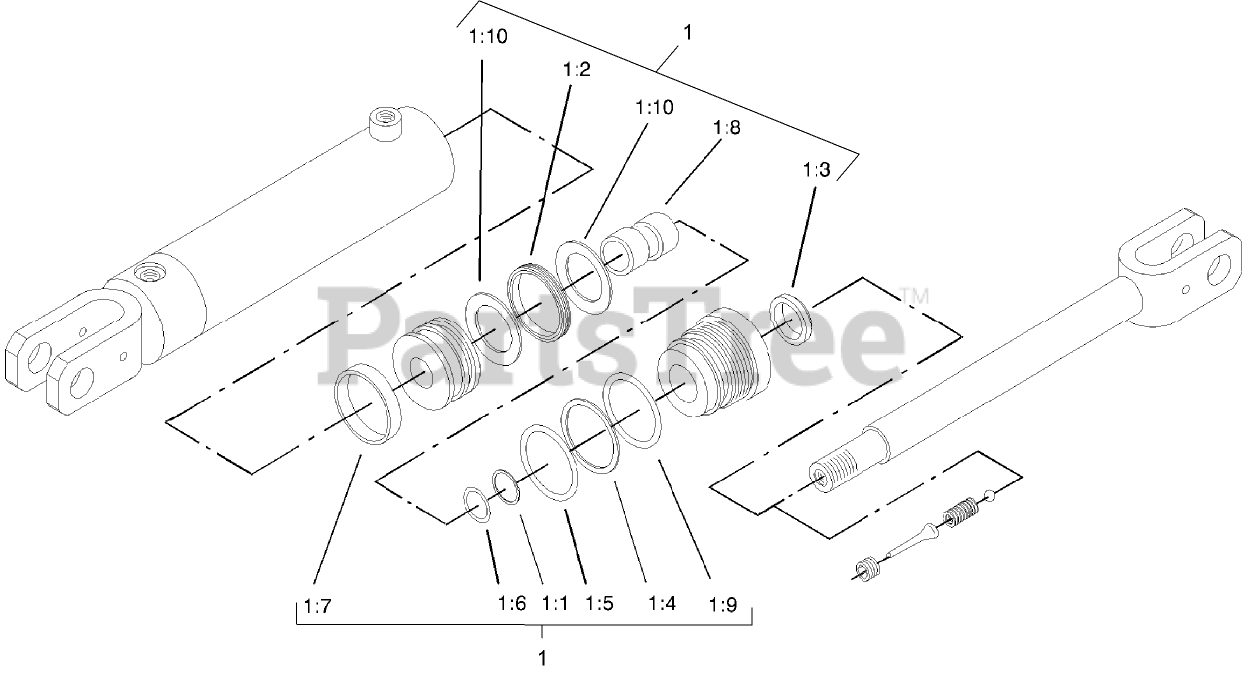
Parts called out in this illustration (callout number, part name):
1	SEAL KIT
1:1	Washer-Backup
1:2	Seal ASM
1:3	Rod-Wiper
1:4	Washer-Backup
1:5	Seal-Dust
1:6	Seal ASM
1:7	Ring-Wear
1:8	Ring-Wear
1:9	Seal-Dust
1:10	Washer-Backup
